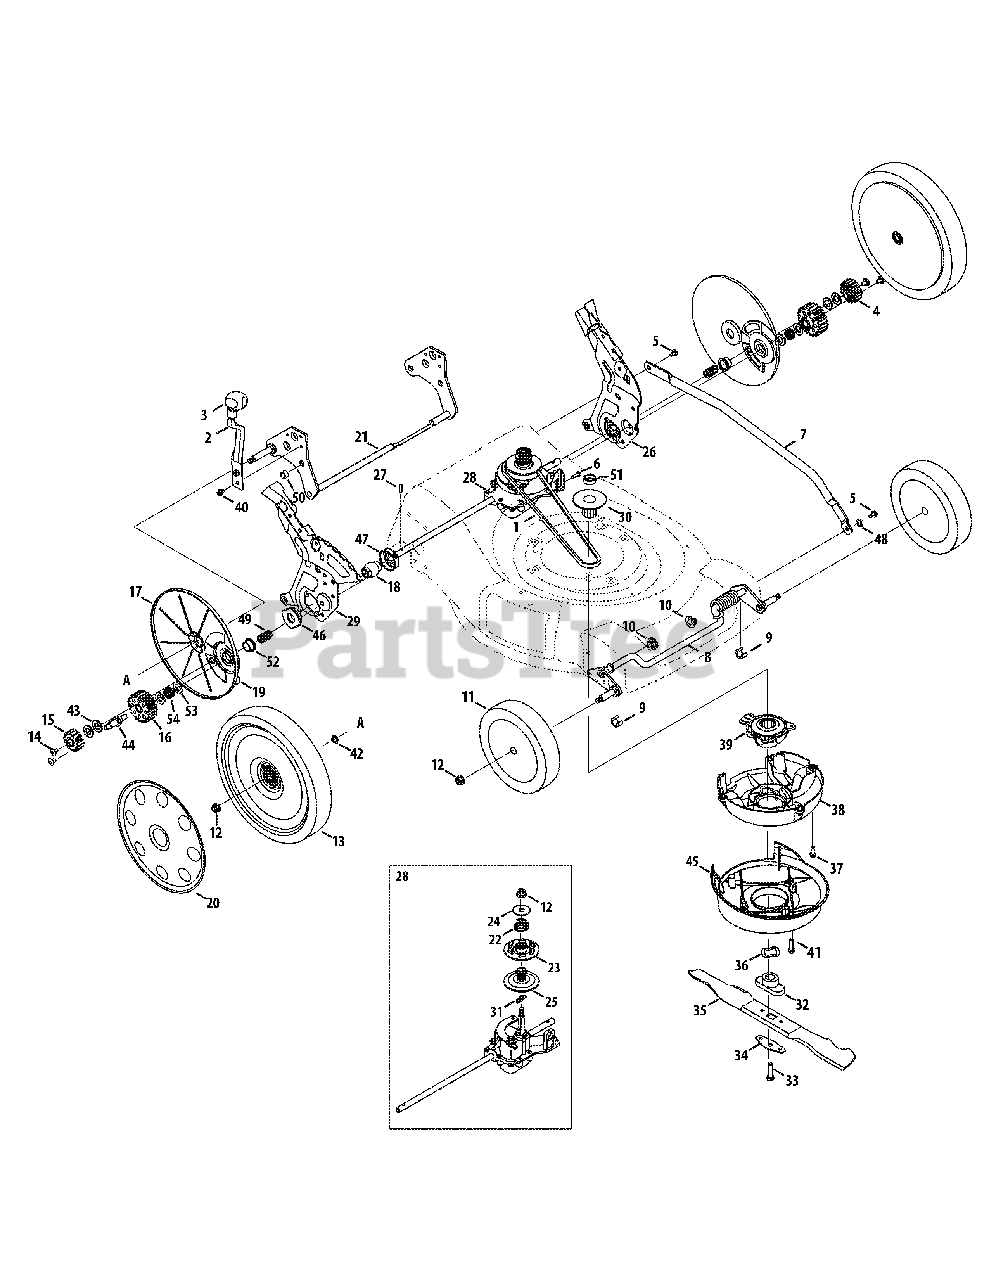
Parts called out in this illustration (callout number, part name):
2	Spring Lever
3	Height Adjuster Knob - Red
4	Spur Gear, 16T - LH
5	Shldr. Screw, 1/4-20 x 0.50
6	Screw, 1/4-15 x .750
8	Front Bracket Assembly
9	Clip Spacer
10	Split Hex Flange Bearing
11	Front Wheel
12	Flange Lock Nut, 3/8-16
13	Rear Wheel
14	Screw, 1/4-20 x .39
15	Spur Gear, 16T - RH
16	Gear, Spur, 23T
17	Wheel Dust Cover
18	Bearing Sleeve
19	Dust Cover Seal Plate
21	Rear Bracket Assembly
22	Compression Spring
23	Upper Pulley
24	Flat Washer, .442 x 1.38 x .060
25	Lower Pulley
26	Handle Bracket Assembly LH
27	Dowel Pin
28	Transmission Assembly
29	Handle Bracket Assembly RH
30	Pulley, Half
31	Extension Spring
32	Blade Adapter
33	Screw, 3/8-24 x 1.50
34	Blade Bell Support
35	21" Mulching Blade
36	Washer, Wave, 1.5 x 1.0 x .029
37	TT Screw, 1/4-20 x .500
38	Engine Baffle
39	Lower Pulley Assembly
40	Screw, TT, 1/4-20 x .375
41	Screw, 1/4-15 x 1.25
42	Washer, Sprg, .500 x 1.00 x .022
43	Washer, Flat, .510 x 1.00 x .060
44	Shf., .500 Dia.
46	Bearing Support
47	Bearing Retainer
48	Wshr, Wave, .385 ID x .598 OD
49	Sprg, Comp., .63 OD x 1.00 Lg.
50	Spacer, .690 x .870 x .150
51	Spcr., 25mm x 1.375
52	Spcr., Flg., .51 ID x .58 OD
53	Washer, Flat, .508 x 1.00 x .020
